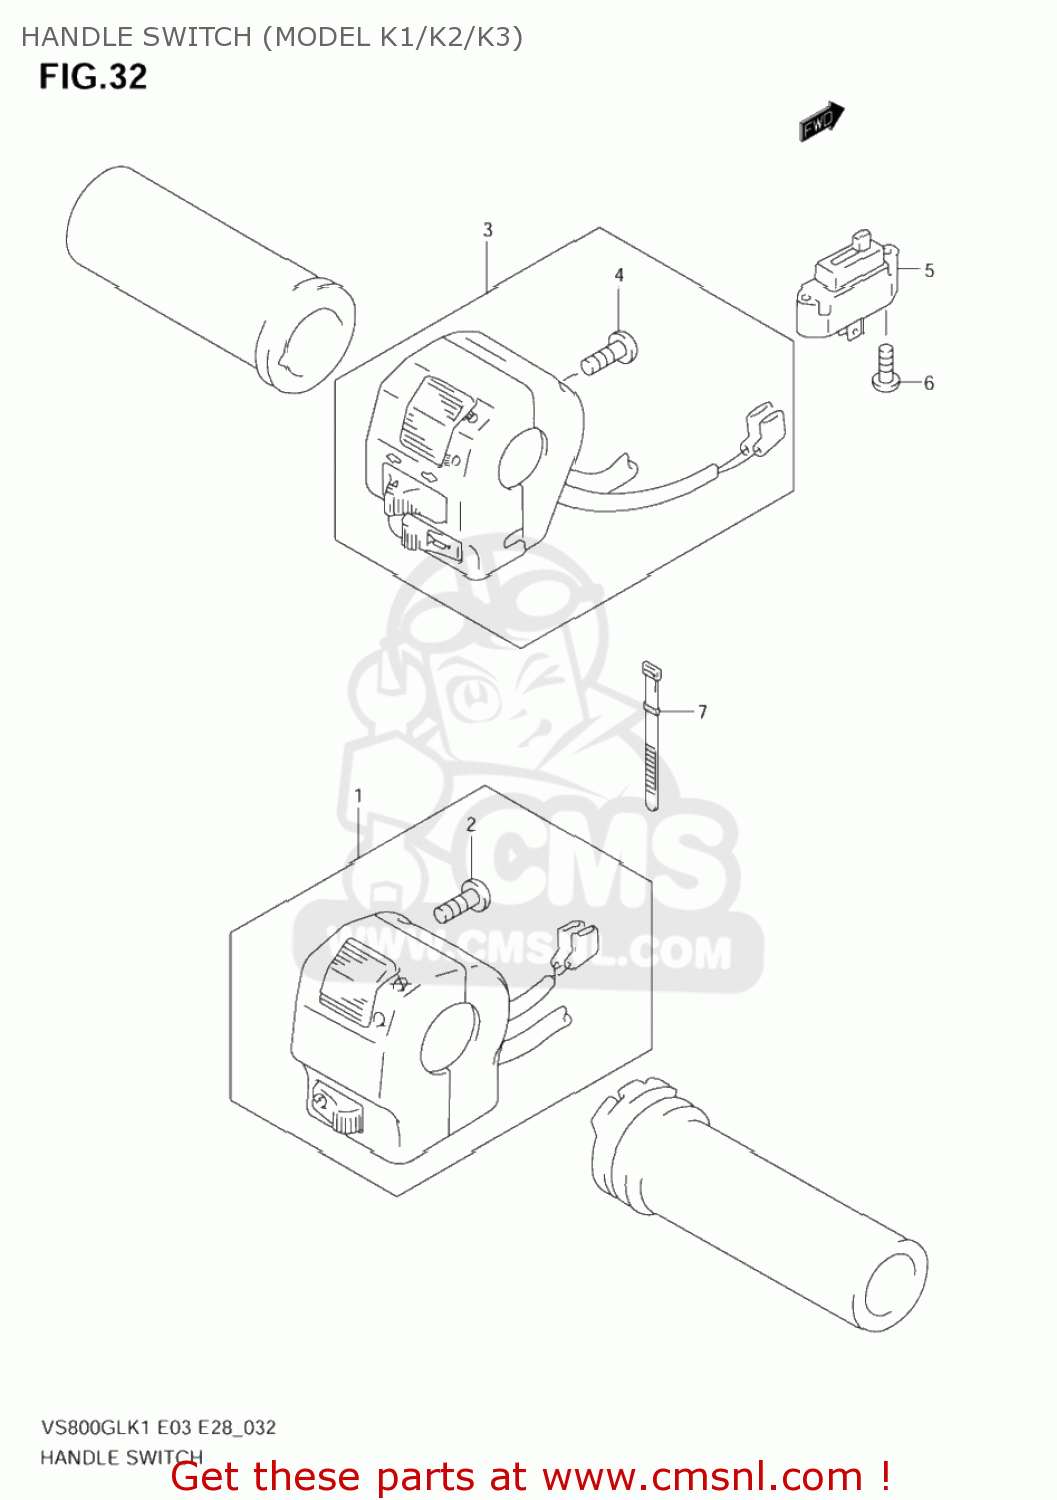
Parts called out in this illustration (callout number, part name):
1	SWITCH ASSY,HANDLE,R
2	SCREW
3	SWITCH ASSEMBLY,HANDLE,LEFT
4	SCREW
5	SWITCH ASSY,CLUTCH
6	SCREW
7	CLAMP
